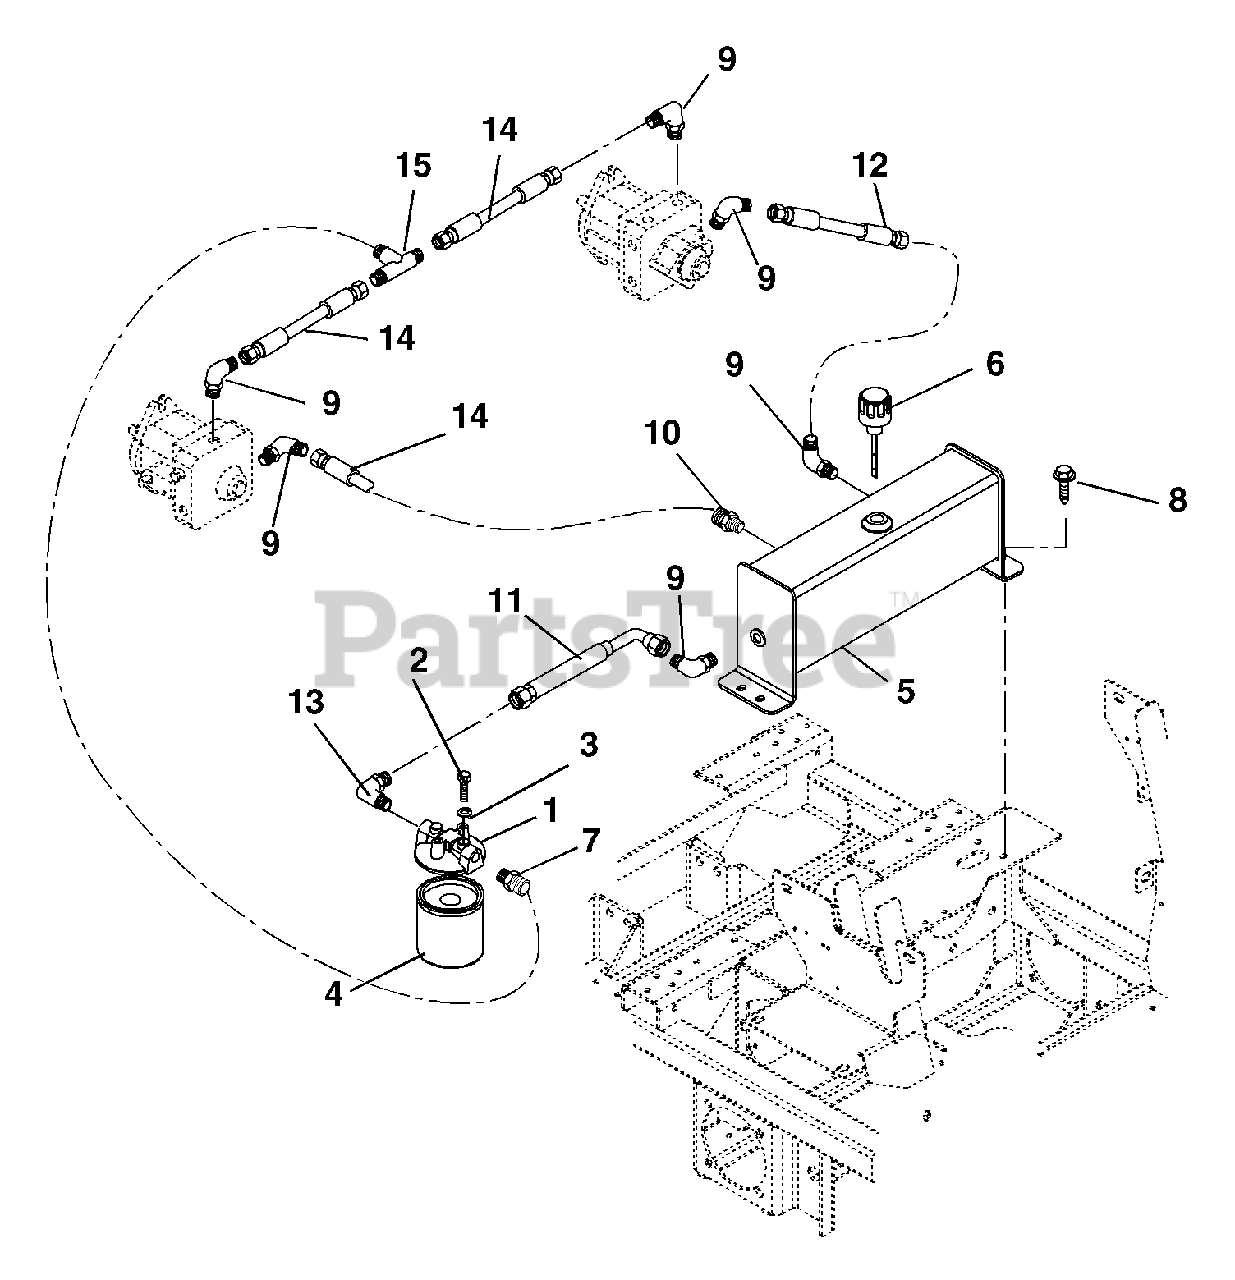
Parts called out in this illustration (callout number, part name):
1	FILTER HOUSING ZINGA ZAF11250
2	@BLT-HEX .25-20X.50 GR5 YWZC
3	@WSHR-LK .25X.062 REG YWZC
4	FILTER ELEMENT, ZINGA AE-25
5	WMT, HYDRAULIC TANK
6	BREATHER, DIPSTICK
7	ADPTR-HYD ST 1 1/16 "O" TO 3/4
8	@SCR-TAP .38-16X.75 HWH TR YWZ
9	ADPTR-HYD EL 3/4 "O" TO 3/4
10	ADAPTER, HYD ST 3/4 "O" TO 3/4
11	HOSE, HYD .50-16-0K F8J0-F8J9
12	HOSE, HYD .50-10-0K F8J0-F8J0
13	ADPT,EL 90DEG .75-16MX1.06-12M
14	HOSE, HYD .50-5-0K F8J0-F8J0
15	FTG HYD TEE M8J-F8J-M8J
